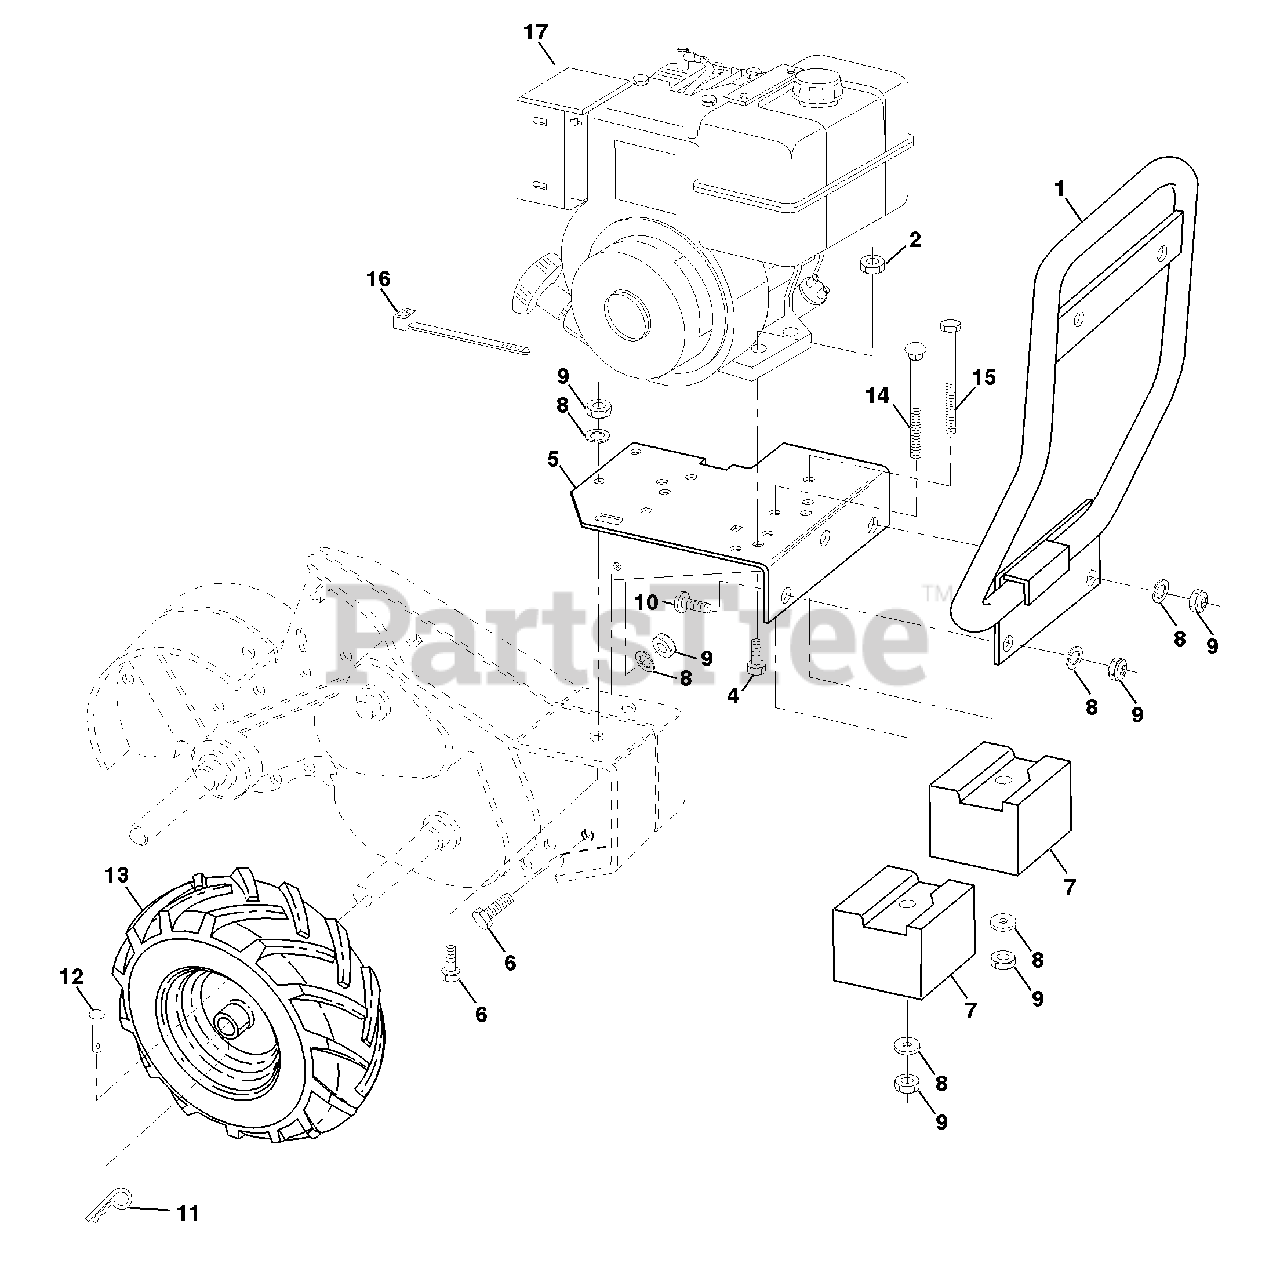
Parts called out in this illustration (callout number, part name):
2	Nut, Keps 5/16-18
4	Bolt, Hex 5/16-18 x 1-3/4
5	Bracket, Engine
6	Bolt, Hex Head 3/8-16 x 1
7	Counter Weight, R.H.
8	Washer, Lock 3/8
9	Nut, Hex 3/8-16
10	Bolt, Carriage 3/8-16 x 1
11	Clip, Hairpin
12	Rivet, Drilled
13	Rim
13	Tire Valve
14	Bolt, Carriage 3/8-16 x 4-1/2
15	Bolt, Hex Head 3/8-16 x 4-1/2
16	Tie, Cable
17	Starter Kit B & S
